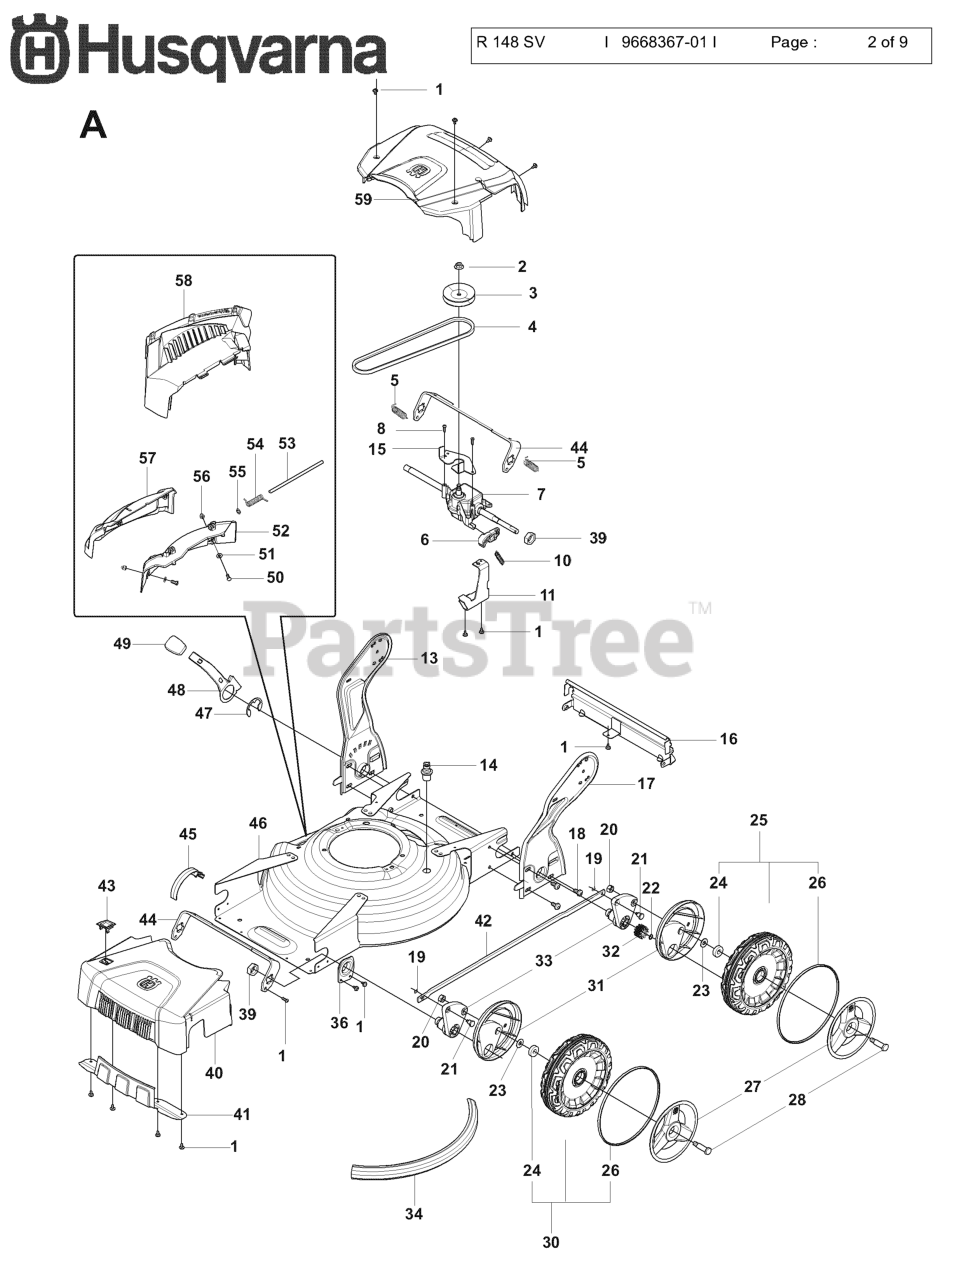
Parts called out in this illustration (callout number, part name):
1	SCREW ITXPANT T50X16 ZN/FE (A
4	BELT WRAPPED V-BELT Z 29.5
8	SCREW ITXPANT T50X16 ZN/FE (A
19	FASTENER
24	BALL BEARING
46	CHASSIS 48S A009 PAINTED
59	REAR COVER A009-2
